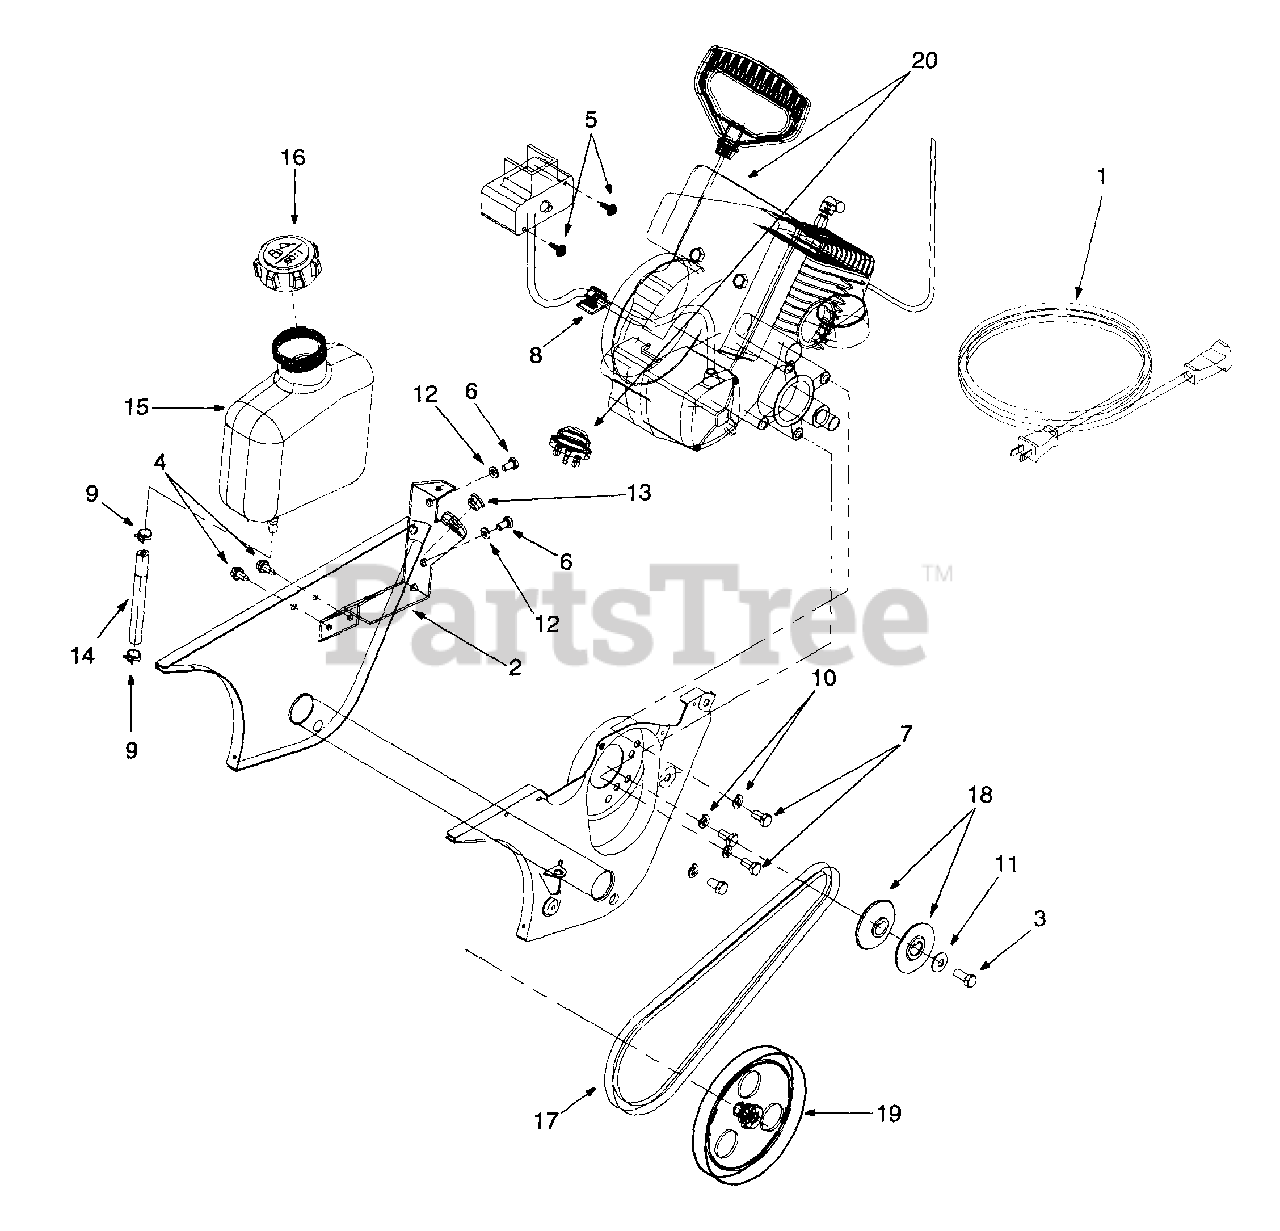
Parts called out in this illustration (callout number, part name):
1	Cord-Extension
4	Screw-Washer
5	Screw-Hex
6	Screw-Hex
7	Screw-Hex Cap
8	Clamp-Mounting
9	Clamp-Hose
10	Washer-Lock
11	Washer-Bell
12	Washer-Lock
13	Bushing
14	Hose-Fuel
15	Tank-Fuel
16	Cap-Fuel
17	V-Belt
18	V-Pulley-Half
19	Pulley
